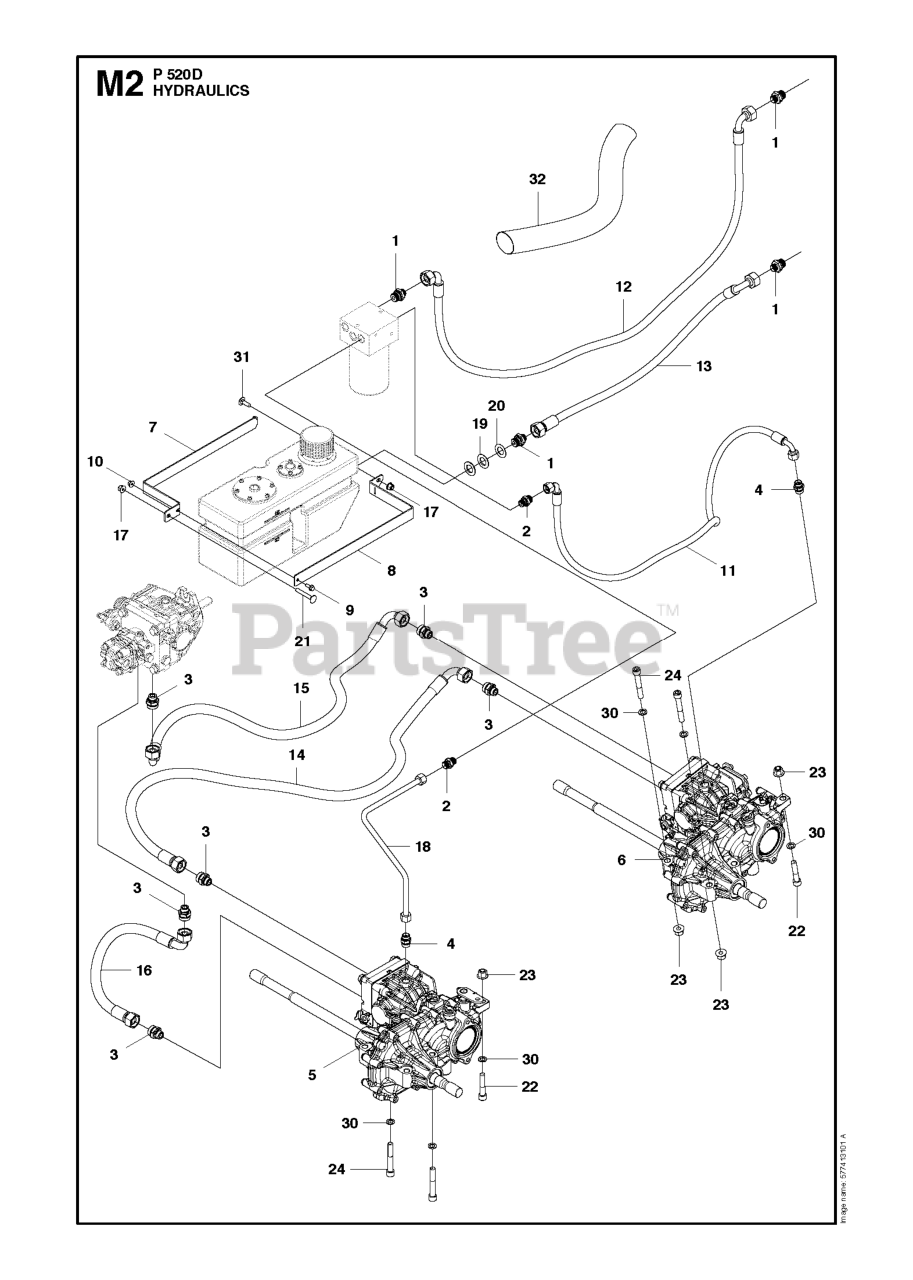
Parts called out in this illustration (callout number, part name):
9	SCREW
10	NUT FLANGE
17	NUT FLANGE
